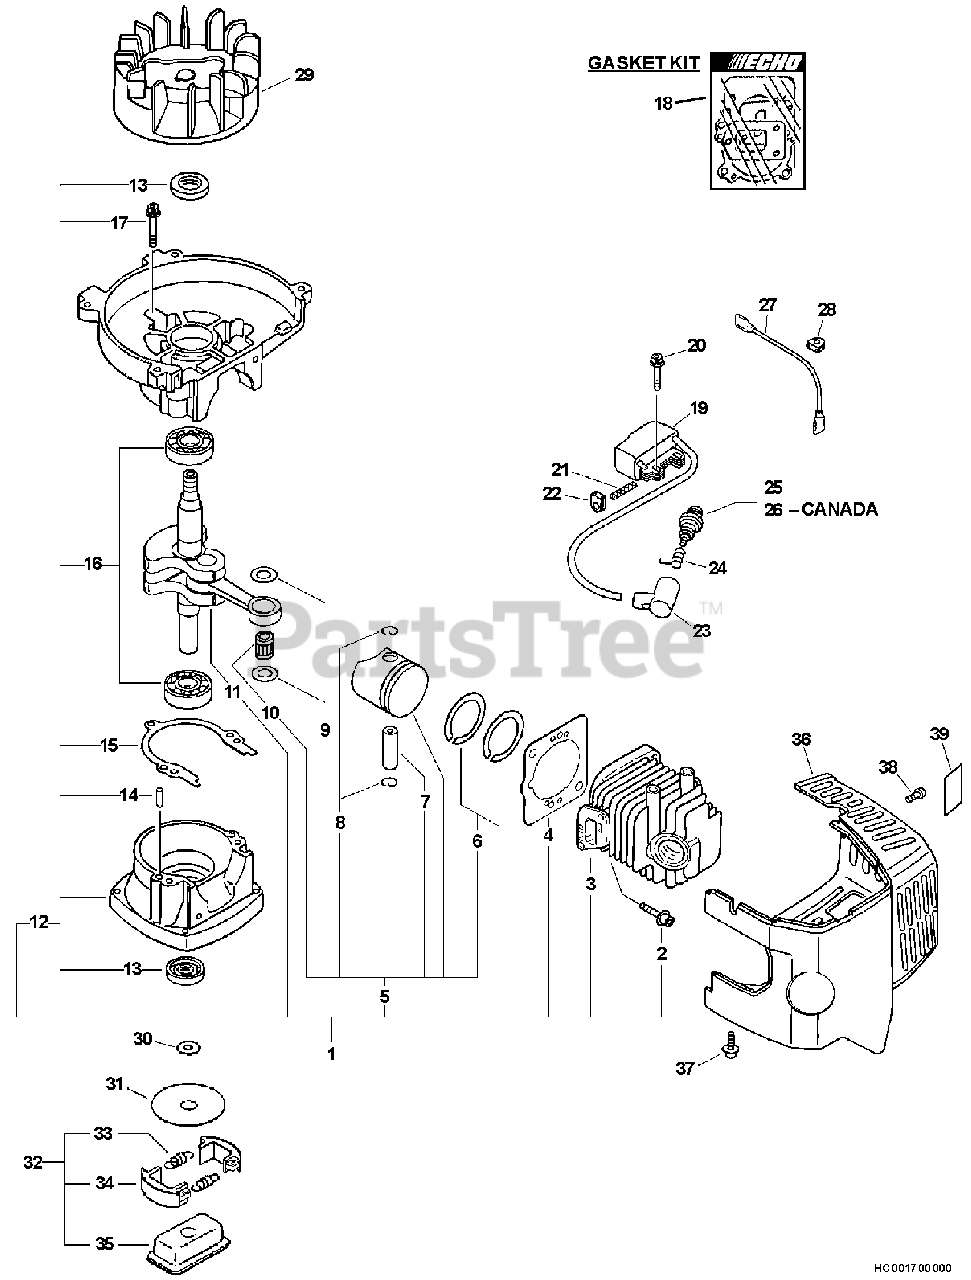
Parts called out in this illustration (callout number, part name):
1	SHORT BLOCK
2	BOLT 5×22
3	CYLINDER
4	GASKET, CYLINDER
5	PISTON KIT
6	RING, PISTON
7	PIN, PISTON 8
8	RING, SNAP
9	WASHER, THRUST
10	BEARING, NEEDLE
11	CRANKSHAFT ASSY
12	CRANKCASE KIT
13	SEAL, OIL 12
14	PIN, LOCATING 4
15	GASKET, CRANKCASE
16	BEARING, BALL - 6201 C3
17	BOLT 5×28
18	GASKET KIT
19	COIL, IGNITION
20	BOLT 4×20
21	TUBE, INSULATOR
23	CAP, SPARK PLUG
24	TERMINAL, SPARK PLUG
25	SPARK PLUG - BPM8Y
26	SPARK PLUG - BPMR8Y
27	LEAD
29	FLYWHEEL
30	WASHER, CLUTCH
31	PLATE, CLUTCH
32	CLUTCH ASSY
33	SPRING, CLUTCH
34	SHOE, CLUTCH
35	BOSS, CLUTCH
36	COVER, ENGINE
37	BOLT 4×20
38	BOLT 4×8
39	LABEL, CAUTION - HOT
